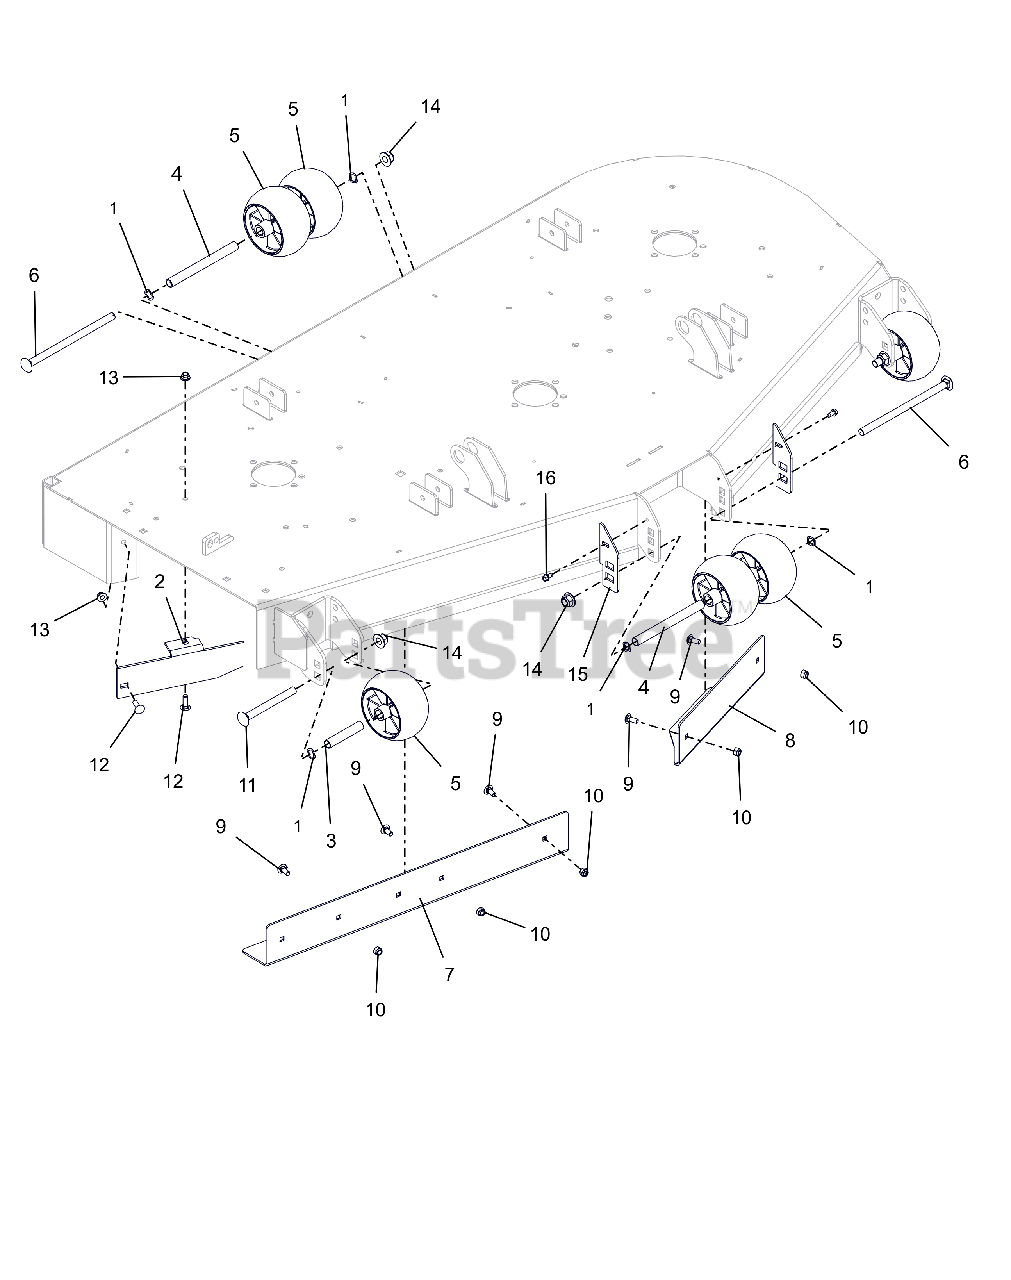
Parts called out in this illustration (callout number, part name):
1	WAVE WASHER .531X.781X.125FH
2	BAFFLE, 60" DISCHARGE
3	SPACER, .510X.625X3.35
4	SPACER, .510X.625X6.50
5	ANTI-SCALP WHEEL - 5X3 CTR
6	BLT, RHSN .50-13X8.50 G5 ZCC
7	BAFFLE, 60" RH VACUUM (ORANGE)
8	BAFFLE, 60" LH VACUUM (ORANGE)
9	BLT,RHSN .31-18X.75 G5 ZCC
10	NUT,NYL .31-18 G5 ZCC
11	BLT, RHSN .50-13X5.00 G5 ZCC
12	BLT,RHSN .31-18X1.00 G5 ZCC
13	NUT,LK-NYL-FLG .31-18 G5ZC120
14	NUT,NYL-FLG .50-13 GF ZCC
15	PLATE, ANTI SCALP WHEEL 60" (ORANGE)
16	SCR-TAP .25-20X.50 HWH ZCC
